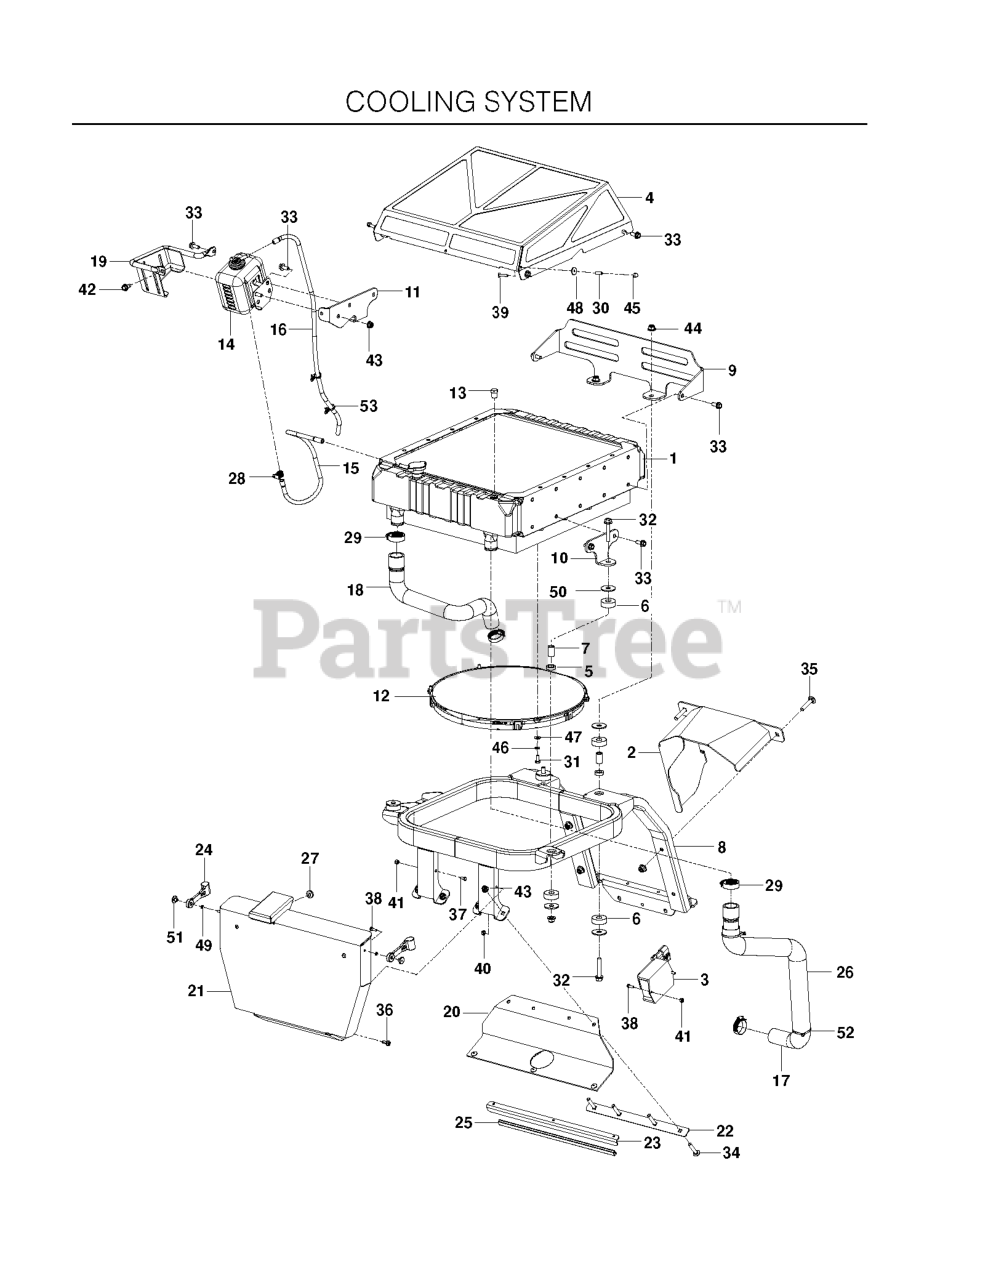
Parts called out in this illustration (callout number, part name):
2	SHIELD, BELT W/DECAL - GR
3	MODULE, FAN REVERSE
4	SCREEN, DEBRIS, BLK
5	ISO-MOUNT INSERT
6	ISO-MOUNT BUSHING
7	ISO MT. BUSHING
8	MOUNT, RADIATOR, GRAY
9	MOUNT, RADIATOR, REAR-BLK
10	MOUNT.RADIATOR.FRONT.BLACK
11	MOUNT, RADIATOR, BLK
12	FAN, ELECTRIC
13	FITTING, PIPE, 1/4 NPT
14	BOTTLE, OVERFLOW
15	HOSE, OVERFLOW, UPPER
16	HOSE, OVERFLOW, LOWER
17	HOSE, RADIATOR, LT
18	HOSE, RADIATOR, RT
19	GUARD, OVERFLOW, BLK
20	GUARD, BELT
21	GUARD, HOSE W/DECALS
22	STRAP, GUARD
23	STRAP, BELT GUARD, BLK
24	HOOD LATCH
25	RP.FLEX TRIM, BLK-LENGTH 1 FT
26	SLEEVE, HOSE
27	GROMMET, BUMPER
28	CLAMP, WORM GEAR, NO. 4
30	BSHG .202X.75 LG SPLIT ZD SPEC
31	HCS 1/4C X 5/8
32	HHFS 3/8-16 X 2.0 GD 5
33	HHFS 5/16-18 X 3/4
34	RHSNB 5/16-18X1 3/4
35	RHSNB 3/8-16X1-3/4
36	SCREW- 1/4-20 X 5/8
37	HCS #10-24 X 1/2
38	SCREW #10-24 X 5/8
39	SCREW #10-24 X 1-1/8 ZD SPEC
40	JAM NUT 1/4C (2 2 PW01)
41	NUT 10-24 NYLOC
42	BOLT 5/16-18 X 3/4
43	5/16-18 NYLOC FLANGE NUT
44	NUT 3/8-16 HEX FLG NYLOC ZD
45	NUT 10-24 ACORN ZD
46	LOCKWASHER 1/4"
47	WASHER 1/4 SAE
49	WASHER - 3/16 LOCK ZD
50	7/16 HD FLAT WASHER
51	NUT 10-24 WELD PLATED
52	TIE, PLASTIC
53	TIE WRAP, 8-3/8", W/CLIP
